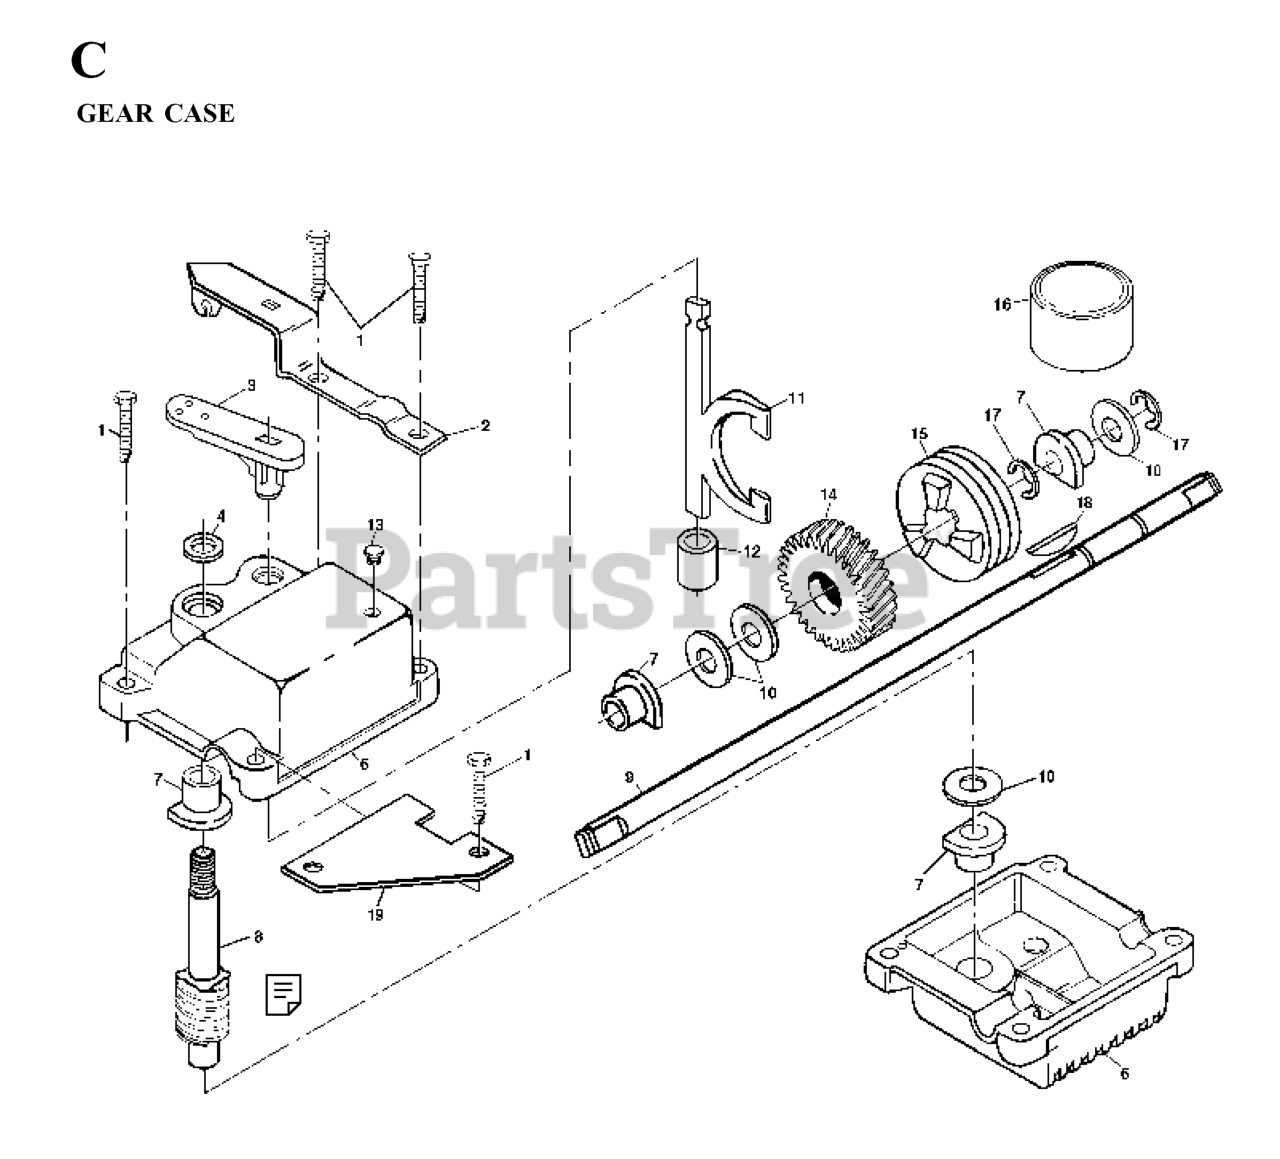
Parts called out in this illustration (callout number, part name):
1	SCREW
2	BRACKET
8	SHAFT WORM
9	CLUTCH JAW
10	THRUST WASHER
11	YOKE.VIBRATORY FINISH.
13	PLUG.AUGER.GEAR.BOX.SNOW
14	GEAR HELICAL
15	CLUTCH JAW
16	GREASE
18	HI PRO KEY
19	BRACKET SPRING
20	WOODRUFF KEY
21	WORM
